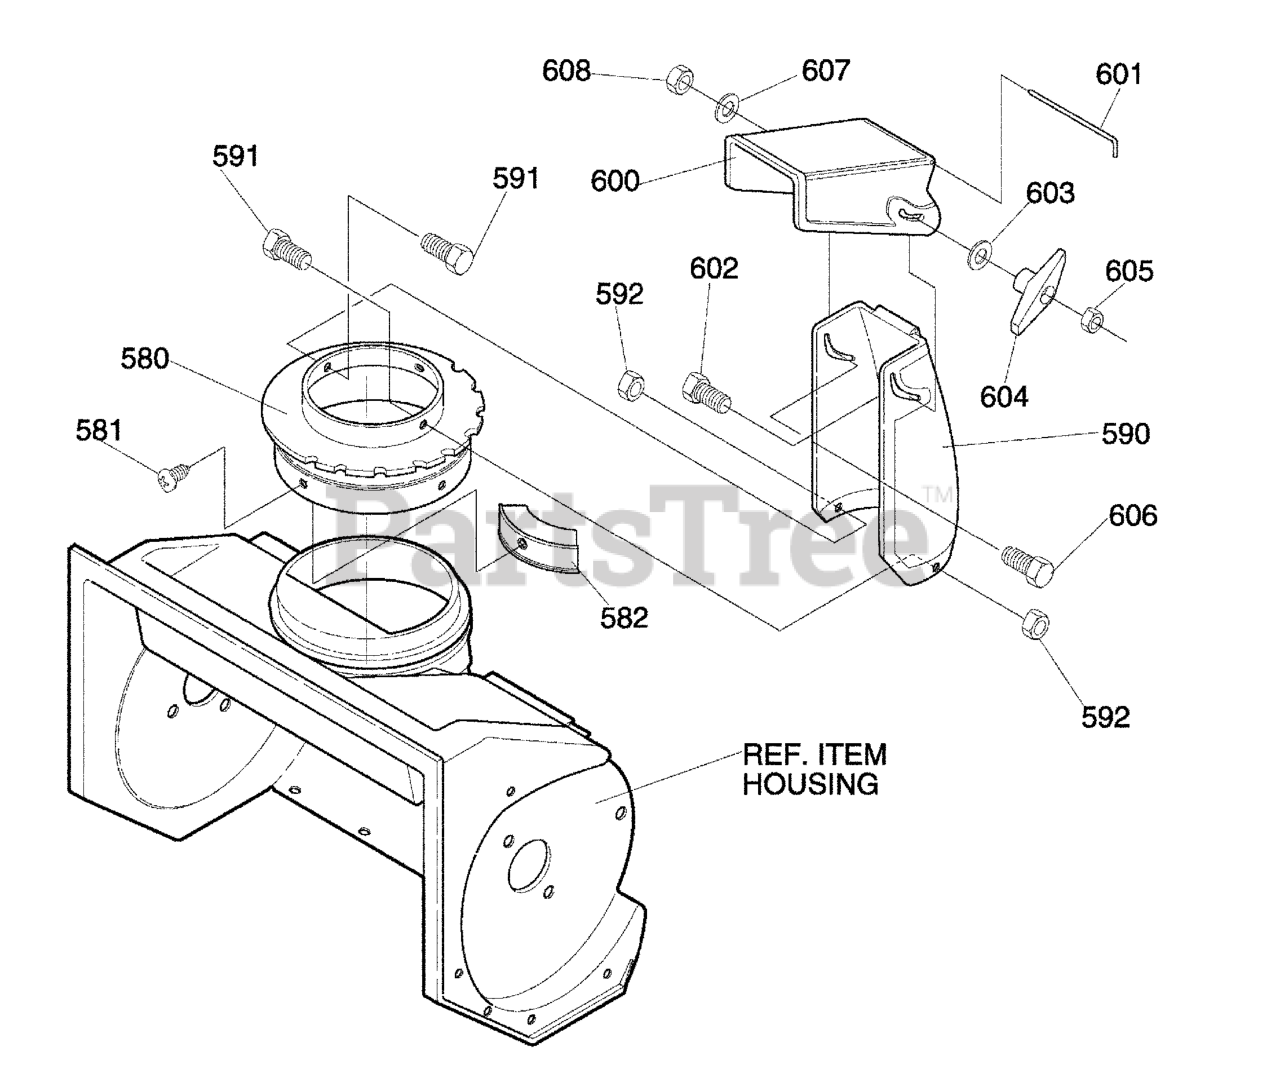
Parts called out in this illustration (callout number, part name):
580	RING, CHUTE
581	SCREW, #10X.50
582	GUIDE, CHUTE
590	CHUTE, LOWER
591	SCREW 1/4-20X.50
592	NUT, 1/4-2
600	CHUTE, UPPER
601	WIRE, HINGE
602	BOLT, 5/16-18X1.25
603	WASHER, FLAT
604	KNOB, T
605	NUT, 5/16-18
606	SCREW, 5/16-18 x 0.75
607	WASHER, FLAT
608	NUT, 5/16-18
